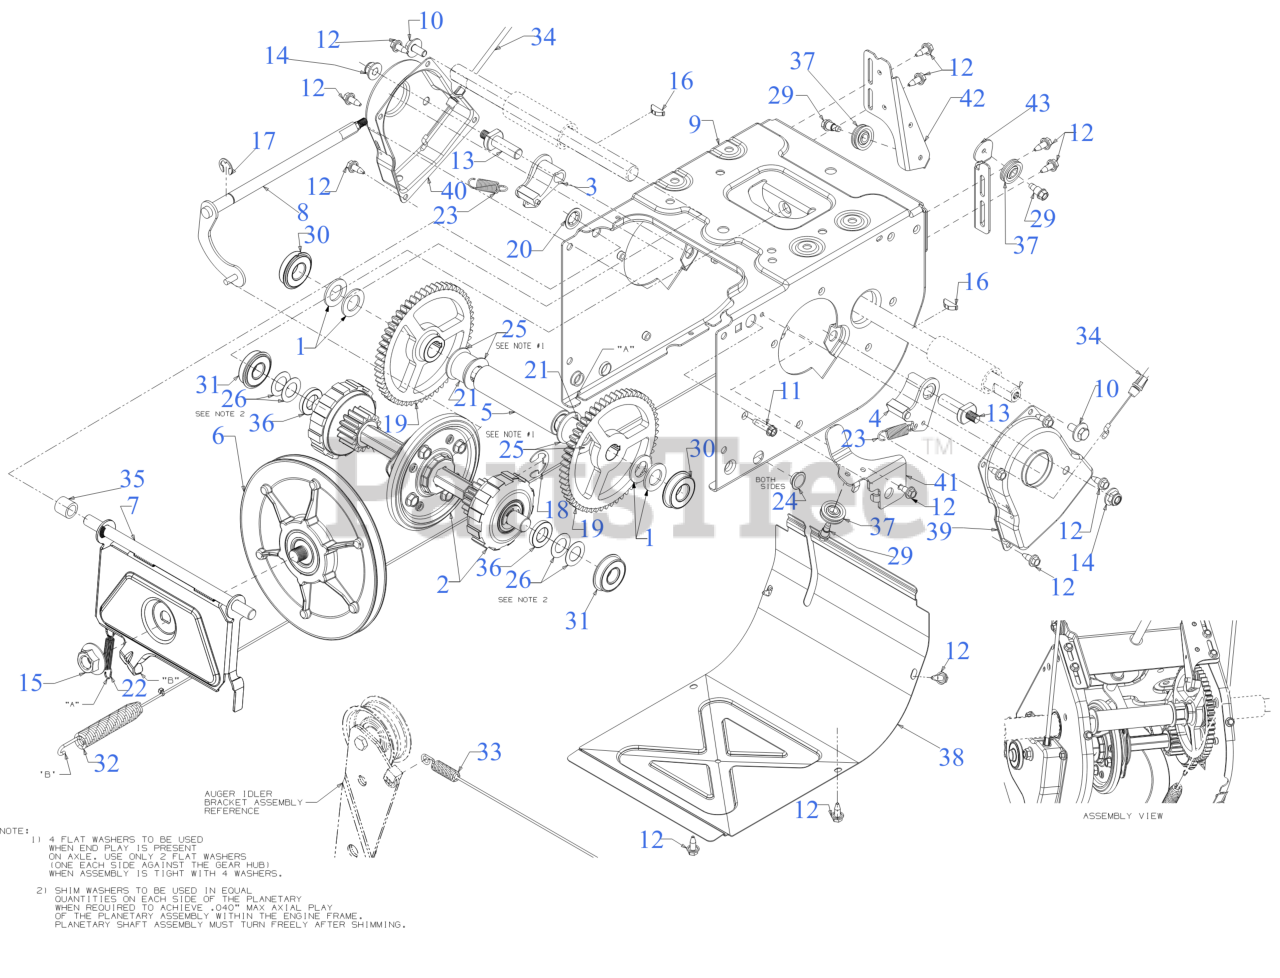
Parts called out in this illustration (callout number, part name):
1	WASHER .764X1.312X.091
2	PLANETARY FRICTION WHEEL HEX SHAFT
3	DOGG ASSEMBLY (RH)
4	DOGG ASSEMBLY (LH)
5	AXLE SUPPORT TUBE ASSEMBLY
6	FRICTION WHEEL DISC ASSEMBLY
7	FRICTION WHEEL BRACKET (POWDER BLACK)
8	SHIFT ROD ASSEMBLY
9	DRIVE FRAME
10	SCREW 5/16-24 x .750 GR5
11	SCREW 1/4-20 x 1.00
12	SCREW 1/4-20X.625
13	ACTUATOR SHAFT
15	FLANGE NUT 5/8-18
16	KEY 3/16 x 3/4
17	E-RING FOR .500 SHAFT
18	RETAINING RING
21	SPACER: .76ID x .75
22	EXTENSION SPRING
23	EXTENSION SPRING
25	FLAT WASHER
26	FLAT WASHER .67X 1.174X .02
29	SHOULDER SCREW
30	BALL BEARING
31	BALL BEARING W/RET
32	WHEEL DRIVE CABLE 44.955"
32	EXTENSION SPRING .55 x 6.25
33	AUGER CABLE 47.48 LG
34	STEERING CABLE
35	SPACER-.513 ID x .703 OD x .69
37	CABLE GUIDE ROLLER
42	CABLE GUIDE BRACKET (DRIVE)
43	CABLE GUIDE BRACKET (AUGER)
